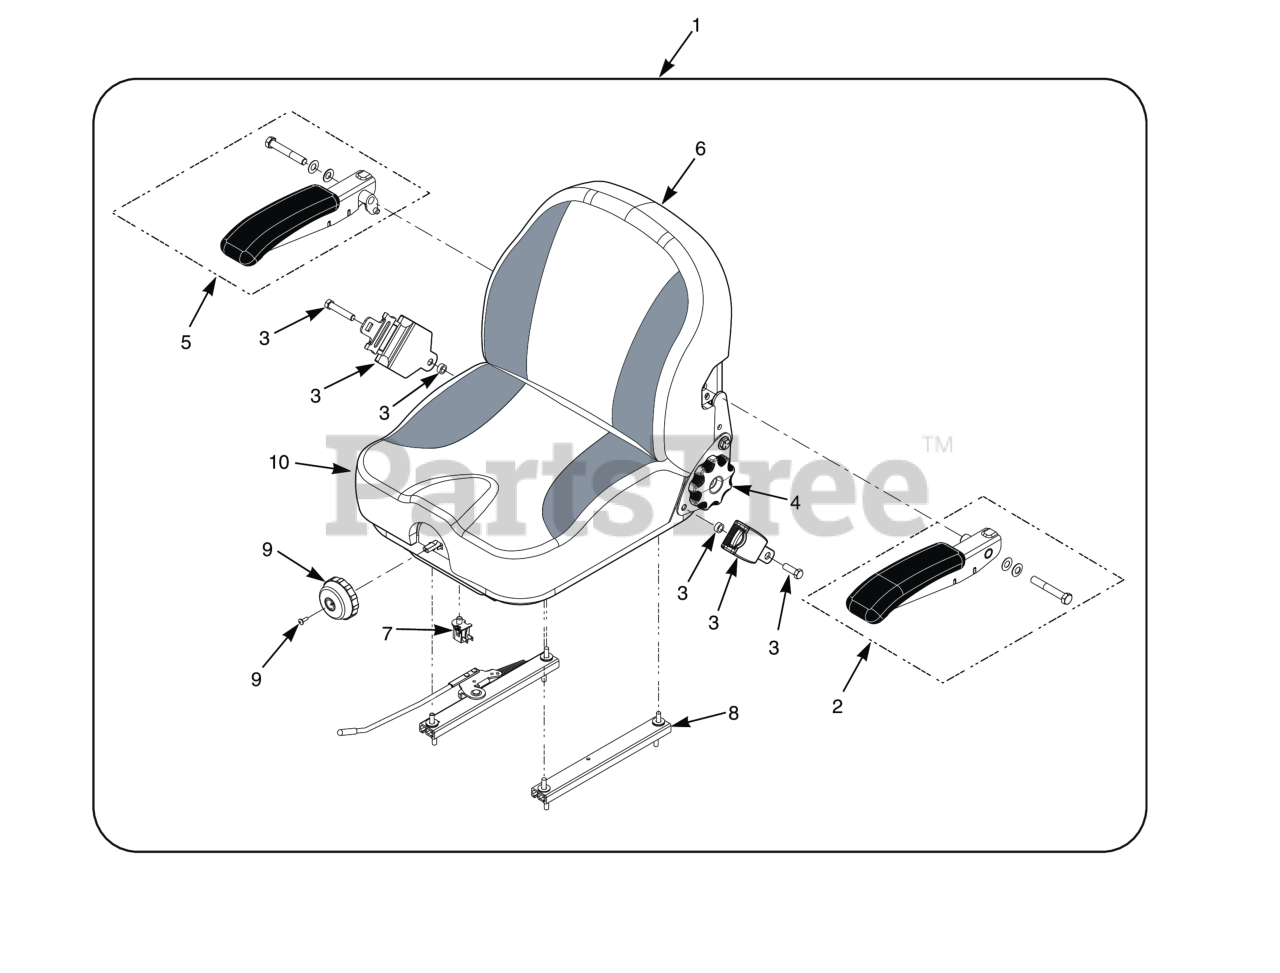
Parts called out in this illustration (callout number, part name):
1	Suspension Seat Assembly w/seat belt
2	Armrest Kit, LH
3	Seat Belt Kit (Suspension Seat)
4	Knob Kit, Recliner
5	Armrest Kit, RH
6	Cover, Back Cushion
7	Switch, Interlock, Normally Open
8	Track Kit
9	Knob Kit, Weight Adjust
10	Cover, Seat Cushion
